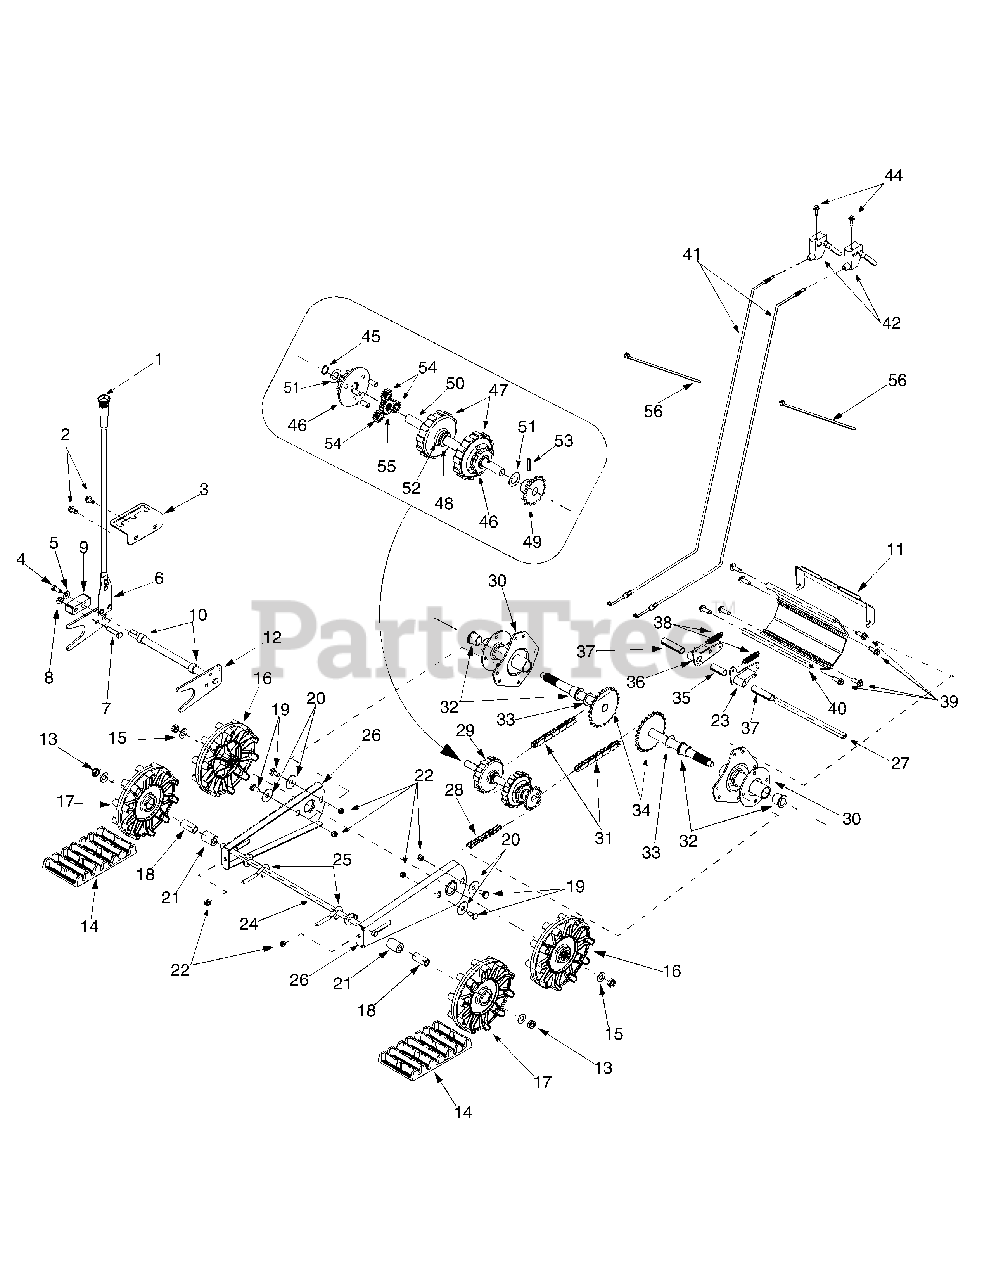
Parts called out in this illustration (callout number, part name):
2	Tap Screw, 5/16-12 x.625
4	Hex Cap Screw, 5/16-24 x.75
5	Bell Washer,.34 ID x.872 OD
7	Hex Cap Screw, 3/8-24 x 1.5
8	Hex Nut, 3/8-24
9	Lift Shaft Drive
10	Spacer,.628 ID x.875 OD x.5
13	Jam Nut, 1/2-20
14	Snow Track
15	Flat Washer,.5 x 1 x.06
16	Track Drive Wheel
17	Track Idler Wheel
18	Spacer,.51 ID x.75 OD x 1.67
19	Screw,.435 x.178-5/16 x.56
20	Flat Washer,.442 x 1.38 x.06
21	Spacer,.51 ID x 1 OD x 1.34
22	Flange Lock Nut, 5/16-18
23	LH Dogg Assembly
25	Eye Bolt, 5/16-18 x 3
27	Actuator Shaft
29	Track/Steering Shaft Ass’y
32	Flange Bearing
33	Flat Washer,.793 x 1.24 x.06
34	Axle Assembly
35	Spacer,.514 x.630 x 1.59
36	RH Dogg Assembly
37	Spacer,.514 x.630 x 2.44
38	Extension Spring
39	Tap Screw, 5/16-18 x 1
40	Track Housing
41	Steering Cable
42	Steering Trigger
44	Screw, #10-24 x 1.375
45	Retaining Ring
46	Carrier Assembly
48	Retaining Ring
49	13-Tooth Sprocket
50	Track Steering Drive Shaft
51	Flat Washer,.58 x 1.06 x.02
52	Flat Washer, 5/8 x 1 x.03
53	Spiral Pin, 3/16 x 1
54	12-Tooth Gear
55	18-Tooth Gear
56	Cable Tie
